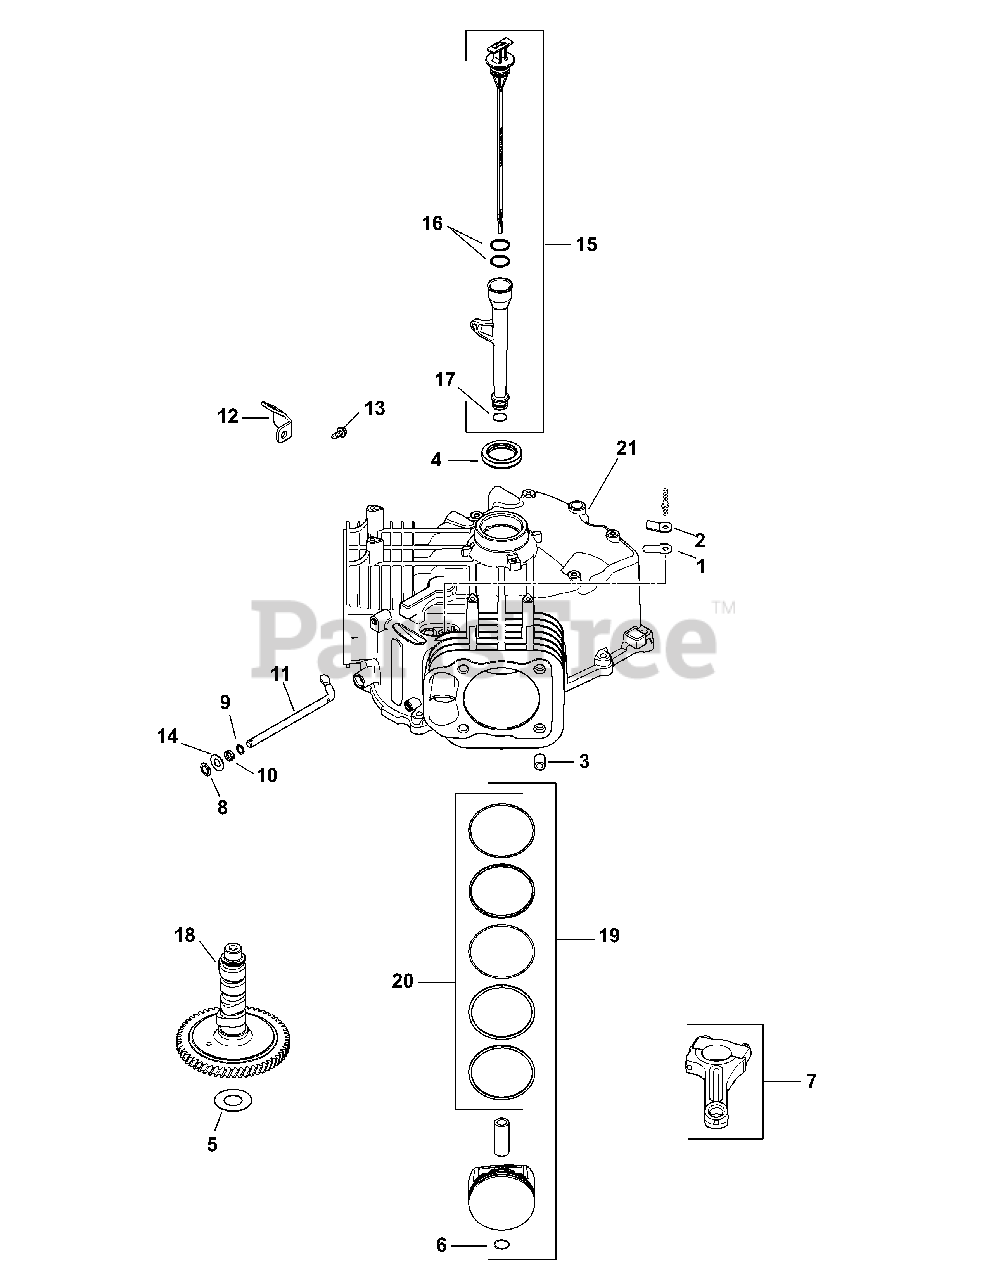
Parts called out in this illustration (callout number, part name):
1	Breather Reed
2	Breather Reed Retainer
4	Oil Seal, 1.78 x 1.26
5	Camshaft Shim (White, .028)
5	Camshaft Shim (Blue, .03)
5	Camshaft Shim (Red, .032)
5	Camshaft Shim (Yellow, .034)
5	Camshaft Shim (Green, .036)
5	Camshaft Shim (Gray, .038)
5	Camshaft Shim (Black, .04)
6	Piston Pin Retainer
7	Connecting Rod (STD)
8	Ring Retainer
9	Flat Washer, 11/32
10	Governor Cross Shaft Seal
11	Governor Cross Shaft
12	Oil Fill Tube Bracket
13	Flange Screw, M5 x .8 x 13
14	Flat Washer, 9mm
15	Dipstick & Tube Kit
17	Lower Oil Fill Tube O-Ring
18	Camshaft Assembly
19	Piston Kit w/ Ring
19	Piston Kit w/ Ring (0.25) 83mm
19	Piston Kit w/ Ring (0.08) 83mm
20	Ring Set, Piston STD
20	Ring Set, Piston (.08)
20	Ring Set, Piston (.25)
21	Crankcase (Use Short Block)
